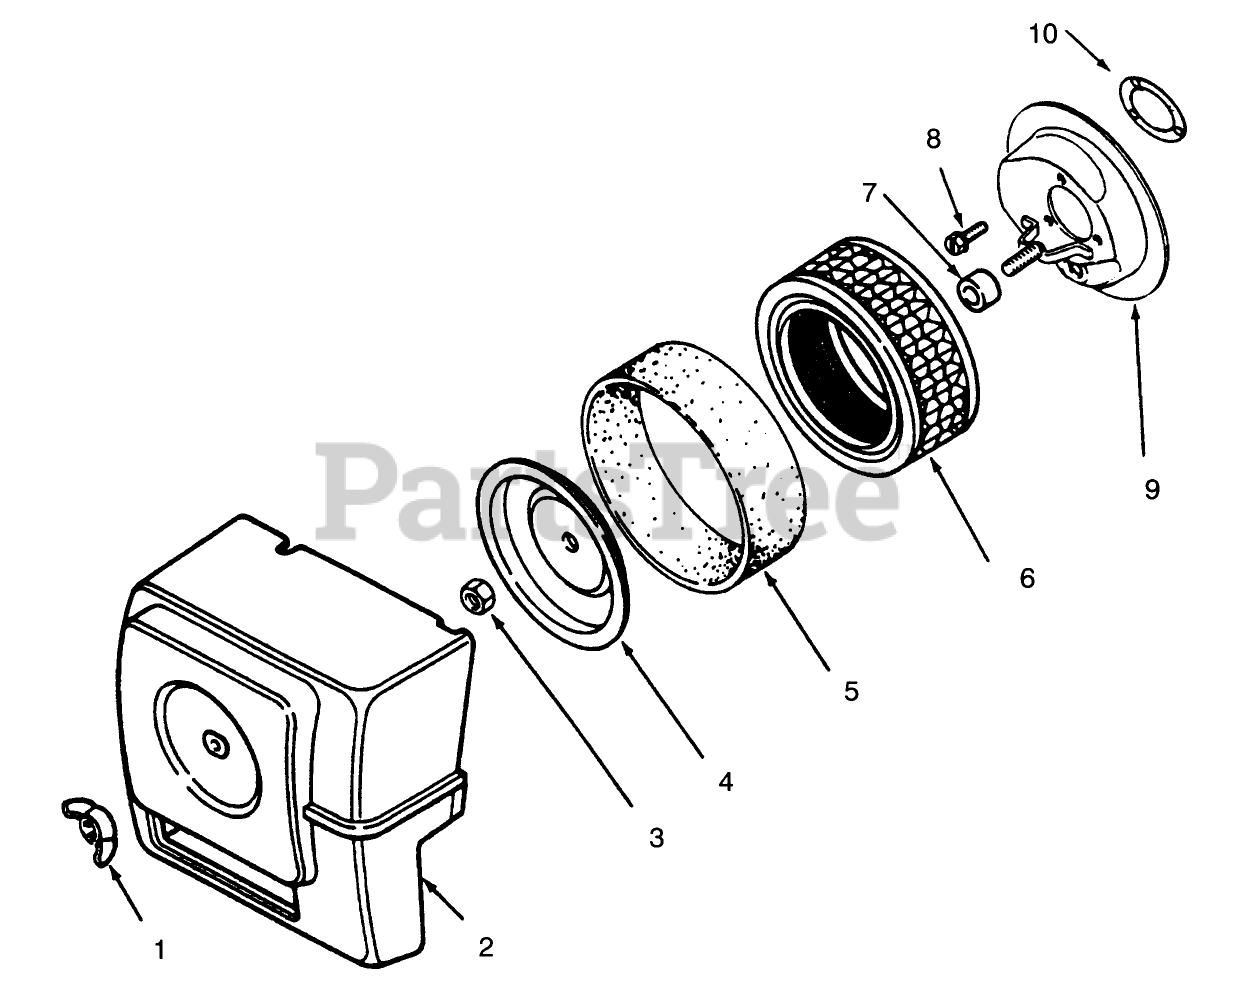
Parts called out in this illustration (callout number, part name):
1	KOHLER X-276-7
2	KOHLER 47-096-10
3	KOHLER 41-100-04
4	KOHLER 52-082-04
5	KOHLER45-083-01
6	KOHLER 45-083-02
7	KOHLER 231032
8	KOHLER X-67-65
9	KOHLER 47-094-20
10	KOHLER 45-041-07
